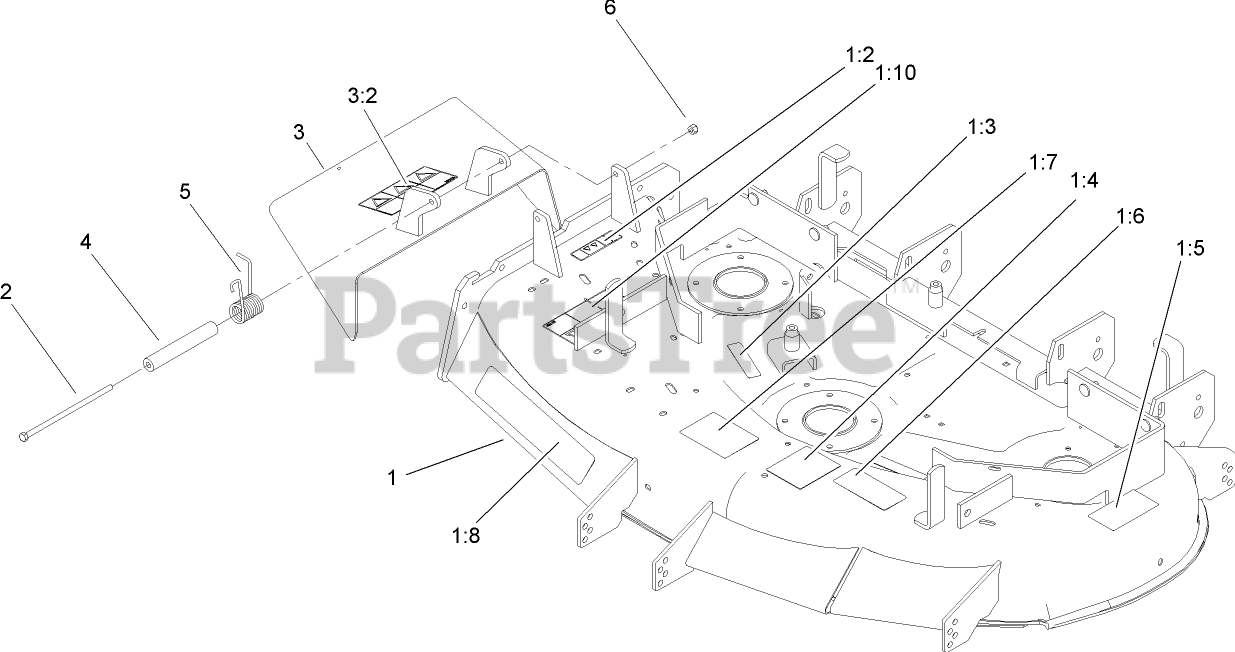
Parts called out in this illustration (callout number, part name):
1	Deck ASM
1:2	DECAL-WARNING, DEFLECTOR
1:3	DECAL-WARNING
1:4	DECAL-ROUTING, BELT
1:5	DECAL-DANGER
1:6	DECAL-TORQUE, BLADE BOLT
1:7	DECAL-ANTI SCALP
1:10	DECAL-DANGER
2	SCREW-HH
3	Deflector ASM
3:2	DECAL-DANGER
4	SPACER
5	SPRING-TORSION
6	NUT-LOCK, NI
